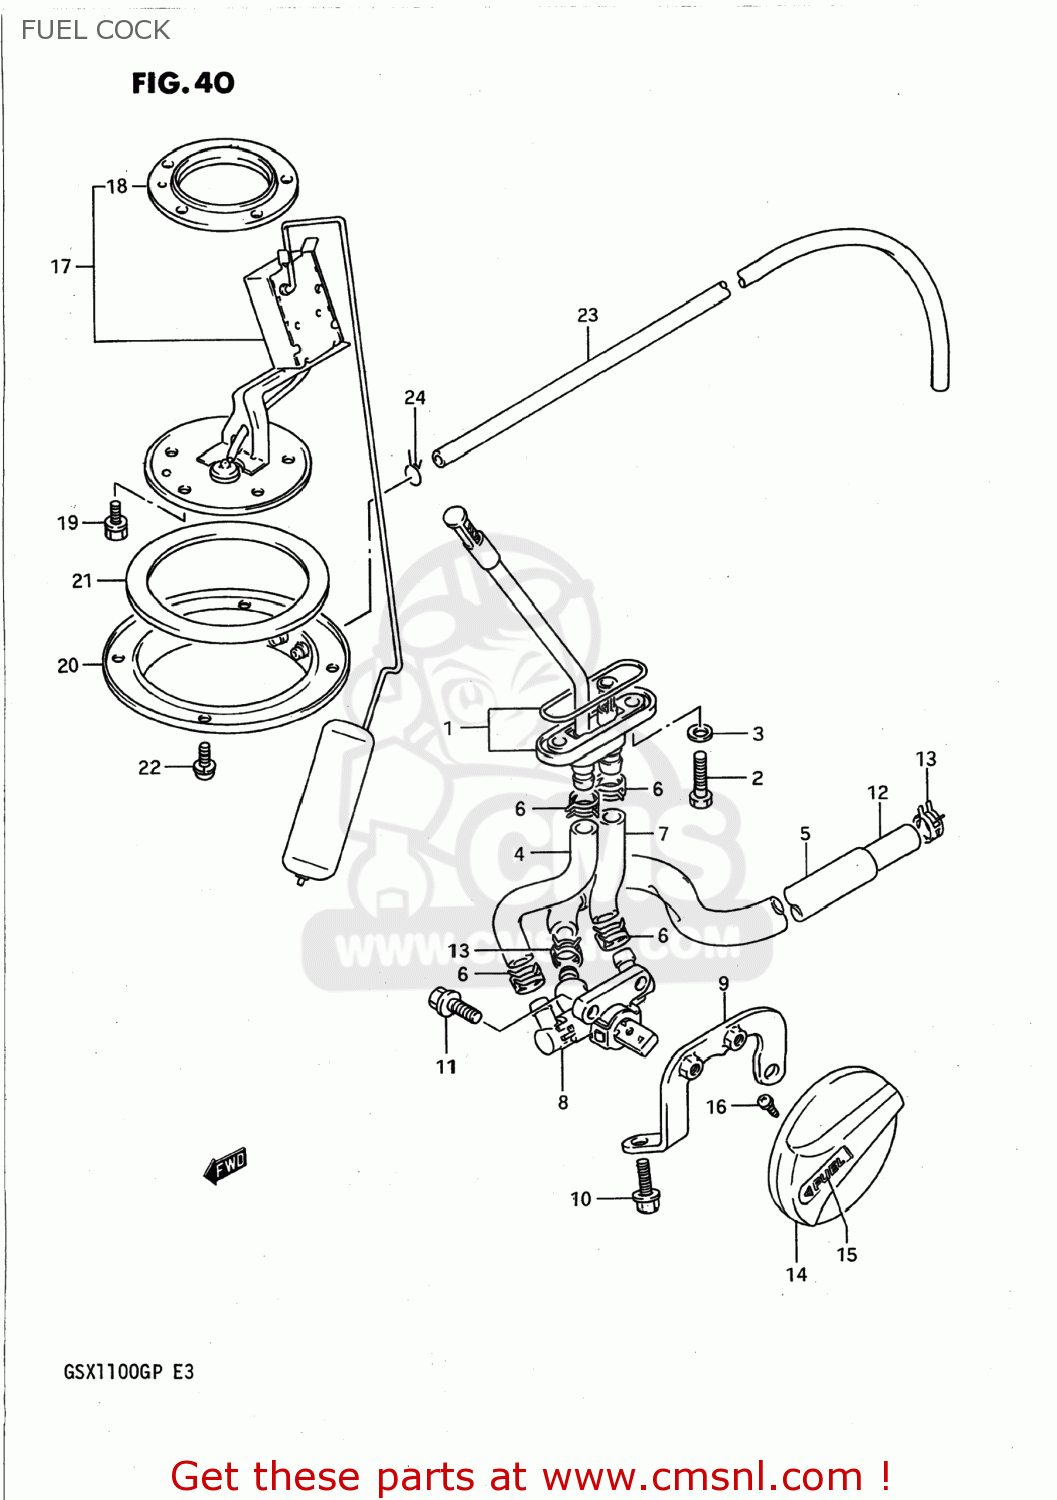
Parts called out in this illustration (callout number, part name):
1	FILTER UNIT,FUEL
2	BOLT(6X20)
3	GASKET(6.4X11.5X0.8) (NAS)
4	HOSE,FUEL ON
5	PROTECTOR(14.5X15.5X600)
6	CLAMP
7	HOSE,FUEL
8	COCK ASSEMBLY,FUEL
9	PLATE,FUEL COCK
10	BOLT,PLATE
11	BOLT 6X16
12	HOSE (7X12X600)
13	CLAMP
14	LEVER,FUEL COCK
15	LABEL,FUEL COCK LEVER
16	SCREW
17	GAUGE ASSEMBLY,FUEL LEVEL
18	GASKET,FUEL LEVEL GAUGE (NAS)
19	BOLT
20	PLATE,FUEL DRAIN
21	GASKET,FUEL DRAIN PLATE (NAS)
22	SCREW
23	HOSE
24	CLIP
